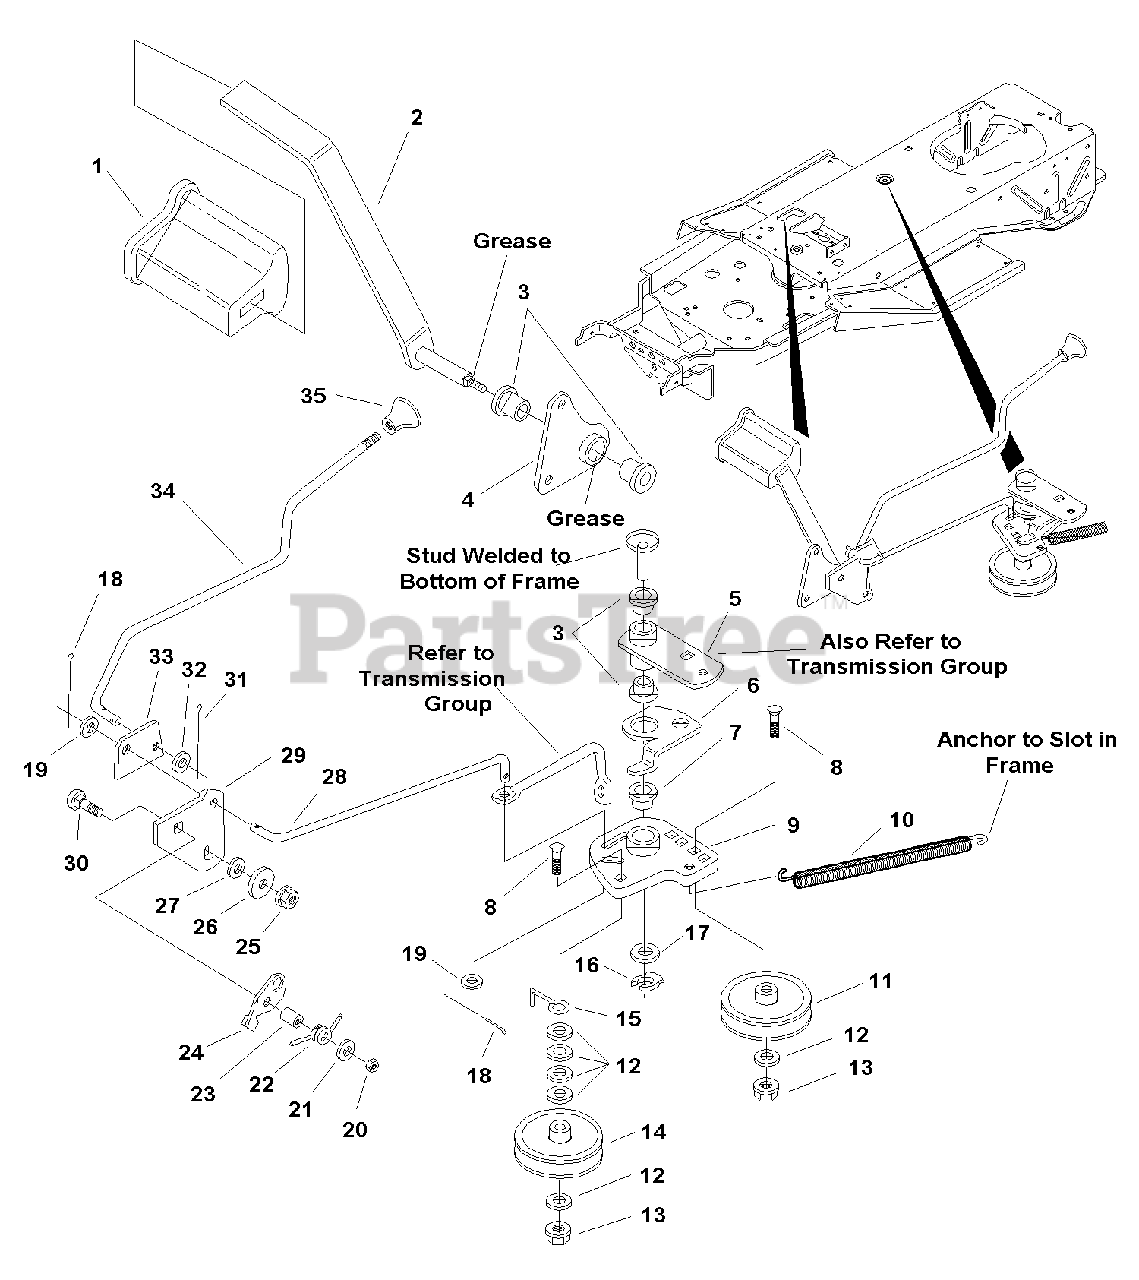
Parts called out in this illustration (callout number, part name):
1	PAD, Foot Pedal
2	PEDAL & SHAFT ASSEMBLY, Brake
5	PIVOT ASSEMBLY, Shift Lever
6	LEVER, Lockout
8	CARRIAGE BOLT, 3/8-16 x 1-3/4
9	ARM & HUB ASSEMBLY, Idler
10	SPRING
11	PULLEY, 3" OD
12	WASHER, 3/8
13	LOCKNUT, Flange, 3/8-16
14	PULLEY, Idler, 3-1/4 OD
16	KLIPRING, 5/8
17	WASHER, 5/8
18	PIN, Cotter
19	WASHER, 5/16
20	LOCKNUT, 5/16-18
21	WASHER, 5/16 x 2-1/8 OD
24	ACTUATOR, Switch
25	NUT, Hex, Large Flange, 3/8-16
26	WASHER, 3/8 x 1-1/4
27	WASHER, 3/8
28	ROD, Clutch
29	ARM, Foot Pedal
30	CARRIAGE BOLT, 5/16-18 x 1-1/2
31	PIN, Cotter
32	WASHER, 1/4
33	CAM, Parking Brake
34	ROD, Park Brake
